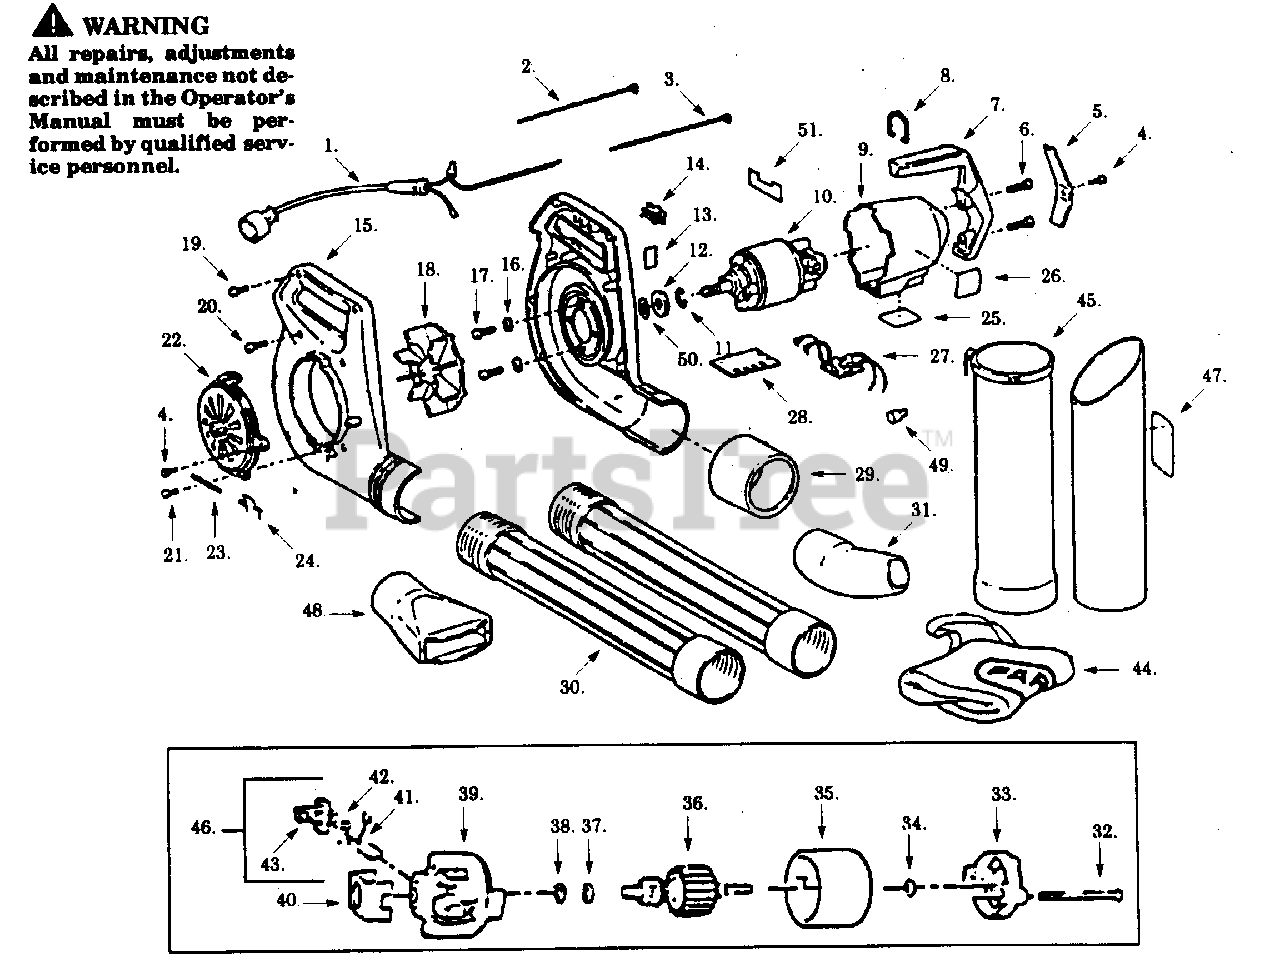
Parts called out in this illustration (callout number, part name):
1	Power Cord Ass'y.
2	Leadwire Ass'y. (Red)
3	Leadwire Ass'y.(Black)
7	Side Handle
9	Motor Cover
10	Motor Ass'y.
11	Retaining Ring
13	Hsg. Front Label (Not a serviceable part)
14	On/Off Switch
15	Housing Set
18	Impeller Ass'y.
22	Inlet Cover Ass'y.
23	Pin Hinge
24	Return Spring
25	Warning Label
26	Motor Cover Label (Not a serviceable part)
27	P.C. Board Ass'y.
28	Mounting Board
29	Ferrule Sleeve
30	Outlet Tube
33	Endbell Ass'y. (Drive)
35	Field Ass'y.
36	Armature Ass'y.
39	Endbell Ass'y. (Brush)
40	Insulator
42	Brush Spring
43	Brush Holder
44	Vacuum Bag
45	Vacuum Tube
46	Brush Kit (Incl. 41,42,43)
47	Warning Label
48	Diffuser Nozzle
49	Crimp Nut
51	Switch Label
